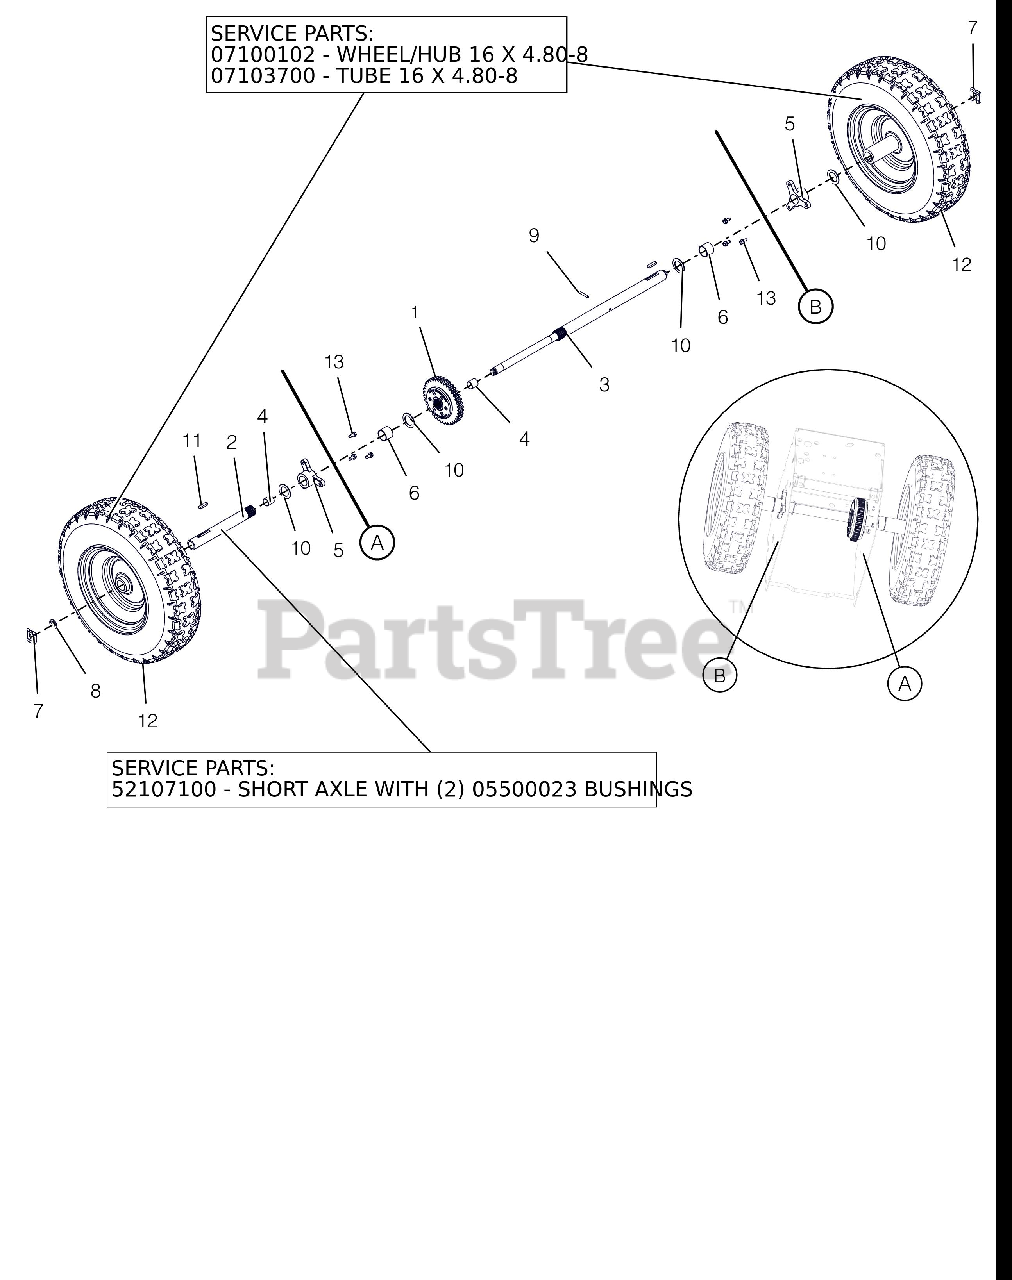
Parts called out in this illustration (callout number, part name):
1	DIFFERENTIAL, AUTOMATIC
2	KIT, SHORT AXLE W/BUSHINGS
2	BSHG-SLV .706X.764X.75 BRZ
3	AXLE, LONG - DIFFERENTIAL
4	BSHG-SLV .706X.764X.75 BRZ
5	BUSHING, AXLE
6	BSHG-SLV, 1.012X1.125X.875
7	CLIP, SNAP .625 DIA
8	RG-RTNG-EXT .625X.042
9	PIN-ROLL .188X1.25
10	WSHR-FL-STL 1.010X1.505X.062YZ
11	KEY-RECT .25X.188X1.00
12	TIRE/WHEEL,16X4.80-8 POLAR TRK
12	HUB, WHEEL - 16X4.8-8 DIFF
12	TUBE
13	SCR-TAP .25-20X.50 HWH TR YWZ
